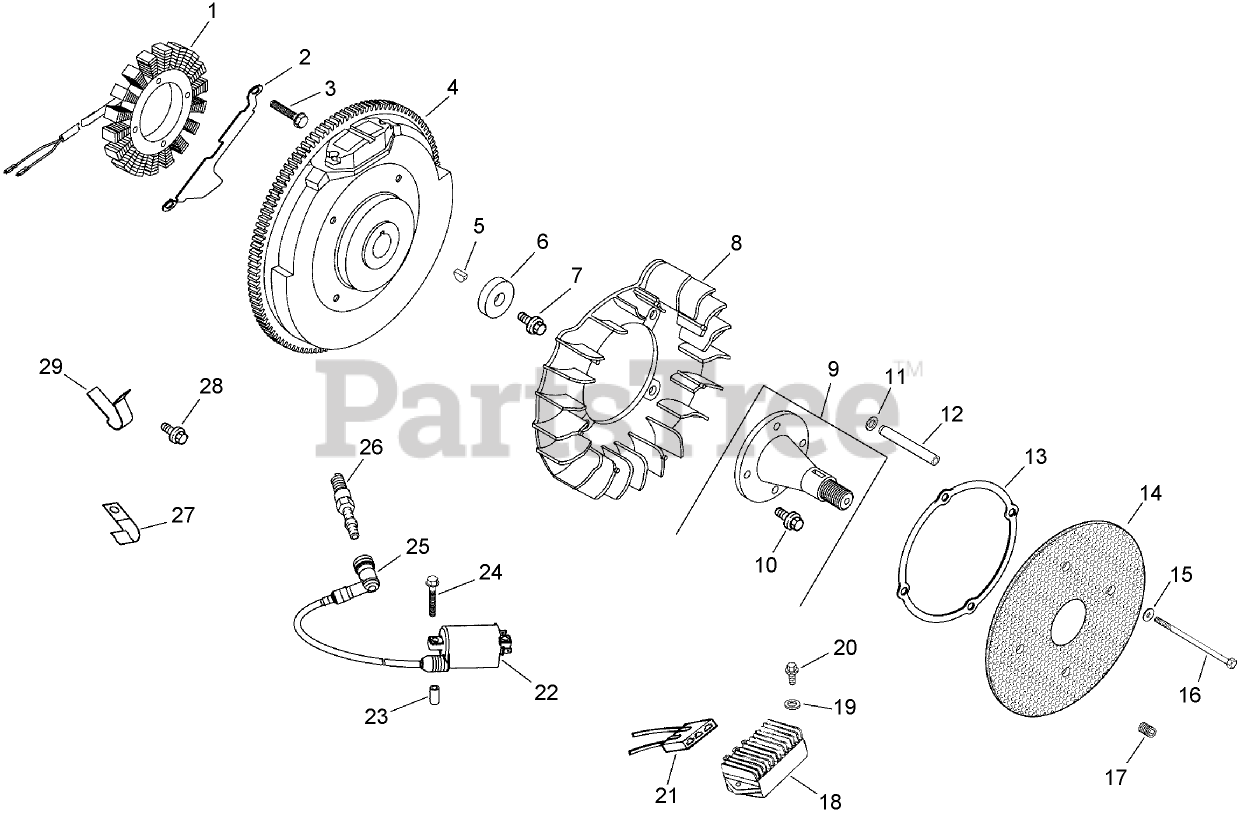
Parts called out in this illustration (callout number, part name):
1	Stator Kit (Includes 3, 21)
2	Bracket-Wire, Stator
3	Screw-Tapping
4	Flywheel
5	KEY (3/16 X 5/8)
6	WASHER-FLAT (13/32)
7	SCREW-FLANGE (M10X1.5X45)
8	Fan
9	Front Drive Shaft Kit (Includes 10)
10	Screw-HF (M8x1.25x25)
11	Washer-Spring (10MM)
12	Spacer
13	Ring-Support
14	Screen-Grass
15	WASHER-FLAT (1/4)
16	Screw-HH (M6x1.0x100)
17	Screw-Set (10-24X.25)
18	Rectifier-regulator
19	WASHER-FLAT (.188)
20	SCREW-PHL HD (11-16X.88)
21	Connector (3 contact)
22	Coil-Ignition
23	Spacer
24	Screw-Tapping
25	Spark Plug Boot ASM
26	SPARK PLUG (PRO SERIES)
27	Clip-Cable
28	SCREW-FLANGE, THREAD FORMING (M5X0.8X16)
29	Clamp-Hose
